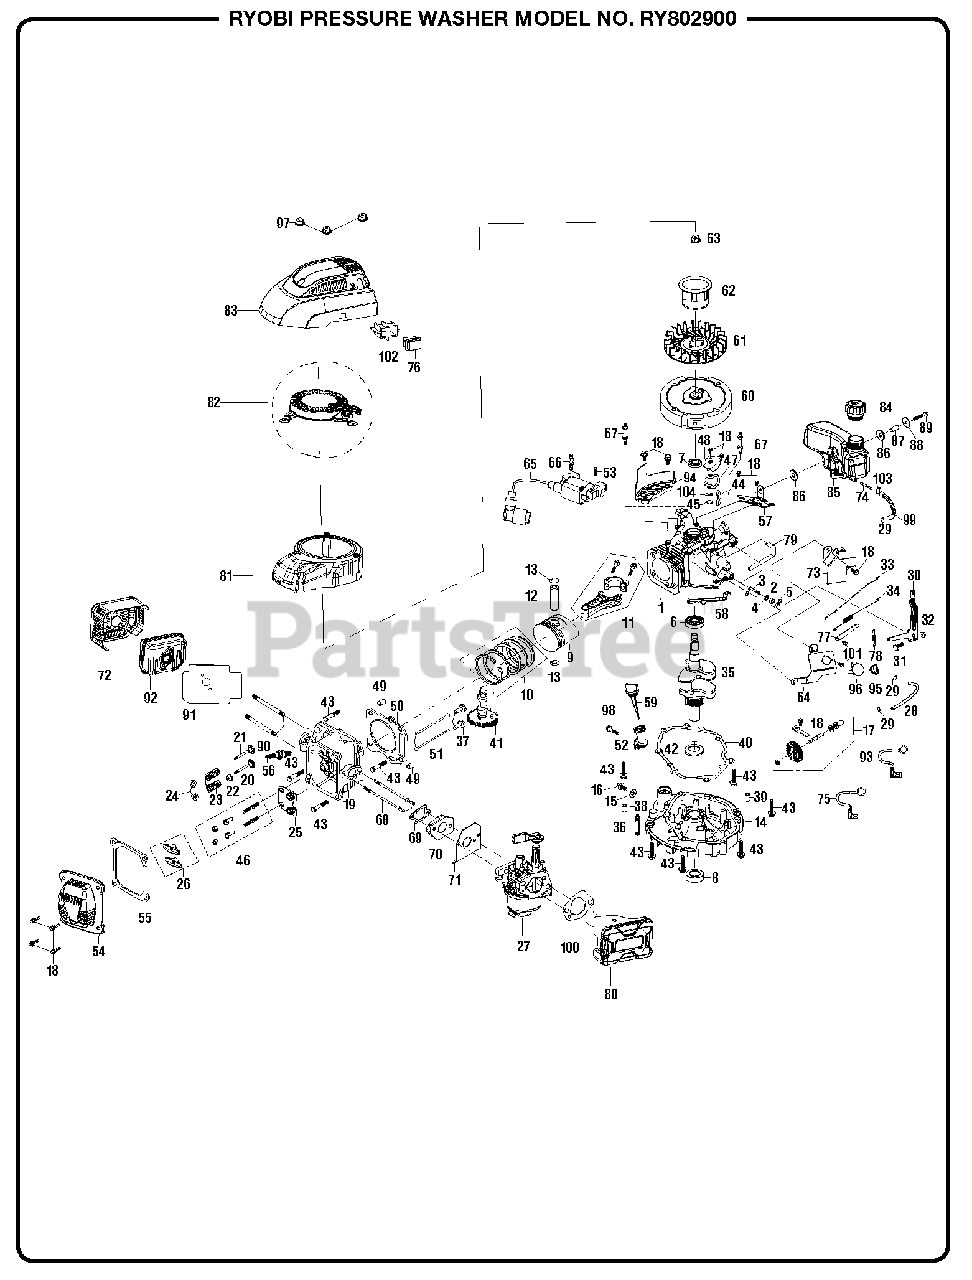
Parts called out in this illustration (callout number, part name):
2	Governor Arm Shaft Seal
3	Governor Arm Shaft
4	Governor Arm Shaft Washer
6	Ball Bearing
10	Piston Scraper Ring Set
11	Connecting Rod Assembly
13	Piston Clip
14	Crankcase Cover Assembly
15	Drain Plug Washer
17	Governor Assembly
18	Bolt (M6 x 12 mm, Hex Flange Hd.)
19	Cylinder Head
20	Inlet Valve
21	Exhaust Valve
22	Intake Valve Returner
23	Valve Spring
24	Valve Spring In Seat
25	Push Rod Guide Plate
26	Rocker Assembly
27	Carburetor Assembly
29	Fuel Line Clip
30	Governor Arm
31	Governor Arm Bolt (M6 x 21 mm, Hex Hd.)
33	Governor Rod
34	Throttle Return Spring
35	Crankshaft Assembly
36	Oil Defense Pipe
37	Valve Lifter
38	Case Cover Dowel Pin
39	Case Cover Dowel Pin
40	Case Cover Packing
41	Camshaft Assembly
42	Crankshaft Washer
43	Bolt (M8 x 50 mm)
44	Breather Filter
45	Breather Valve Cover
46	Rocker Bolt
47	Breather Chamber Gasket
48	Breather Chamber Cap
50	Cylinder Head Gasket
52	Oil Filler Extension
53	Bolt (M6 x 30 mm)
54	Cylinder Head Cover Comp
55	Headcover Packing
57	Oil Tank Stay
60	Flywheel Assembly
61	Recoil Starter Fan
62	Starter Pulley
64	Switch Plate
65	Ignition Coil Assembly
66	Ignition Coil Bolt Stud
67	Recoil Starter Bolt Stud
69	Intake Packing
70	Carburetor Insulator
71	Carburetor Packing
72	Out Muffler Shield
73	Upper Shroud Assembly
75	Flameout Wire
77	Wire Harness Clip
78	Governor Spring
79	Breather Tube
80	Air Cleaner Assembly
82	Recoil Starter Comp
84	Fuel Tank Cap
85	Fuel Tank Assembly
86	Isolation Pad
87	Fuel Tank Bushing
88	Fuel Tank Washer
89	Bolt (M8 x 45 mm)
91	Exhaust Packing
92	Muffler Comp
93	Flameout Wire
95	Fuel Valve Knob
96	Fuel Valve Bezel
98	Bolt (M8 X 20 mm)
100	Carburetor Spacer
101	Bolt (M6 x 25 mm)
102	Switch Bracket
103	Fuel Line Clip
104	Breather Spring
